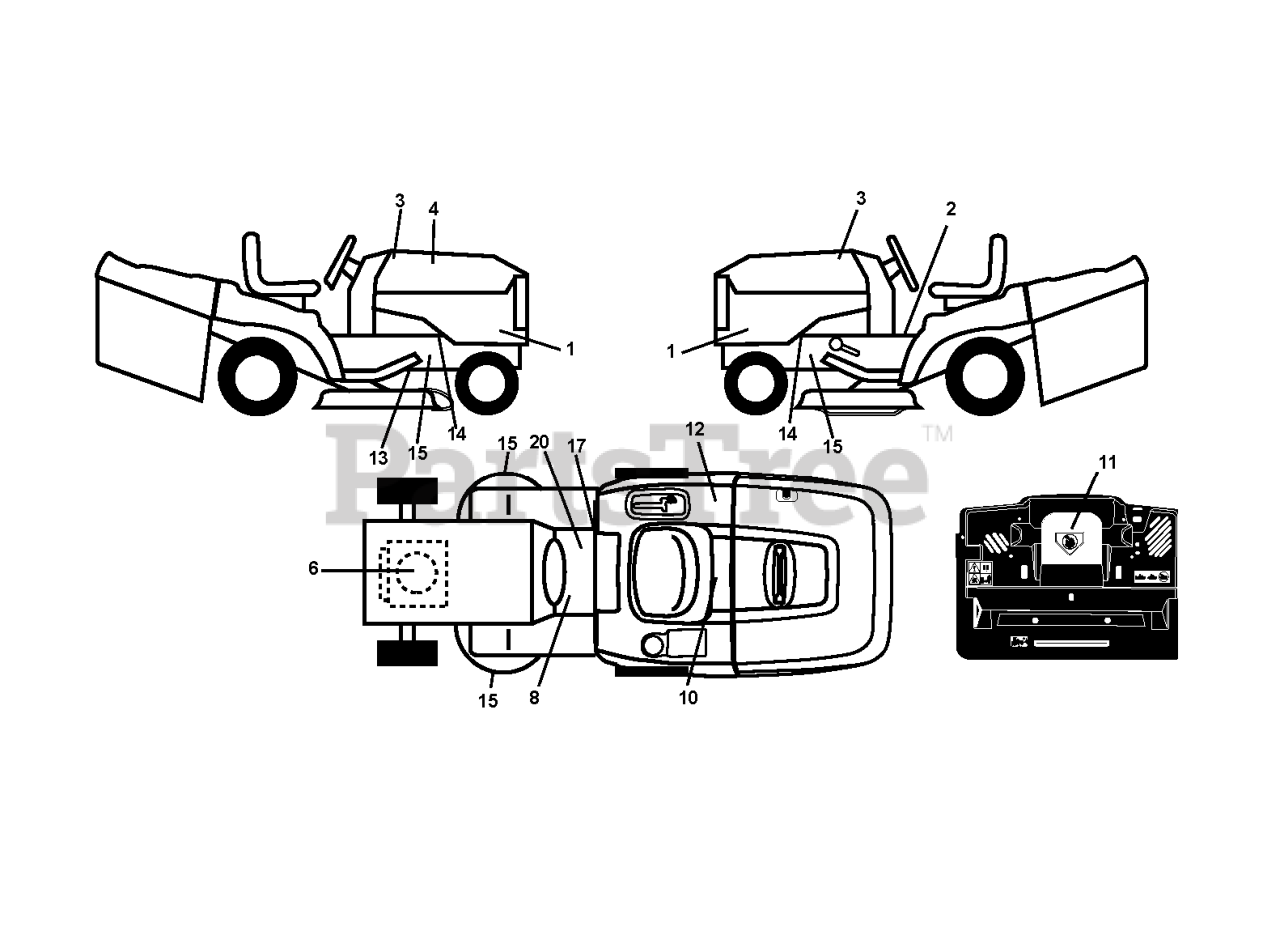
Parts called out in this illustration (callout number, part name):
1	DECAL PANEL
2	LABEL
3	DECAL.HOOD.NAMELOGO.HUSQ
6	DECAL
8	DECAL
10	DECAL BTRY SYMBOLS
11	DECAL.INTERNATIONL.CUTFINGER
12	Decal, Fender 100 DB/CE
17	DECAL PARK BRAKE
20	DECAL.BYPASS.FENDER.CRD.LT.YT
